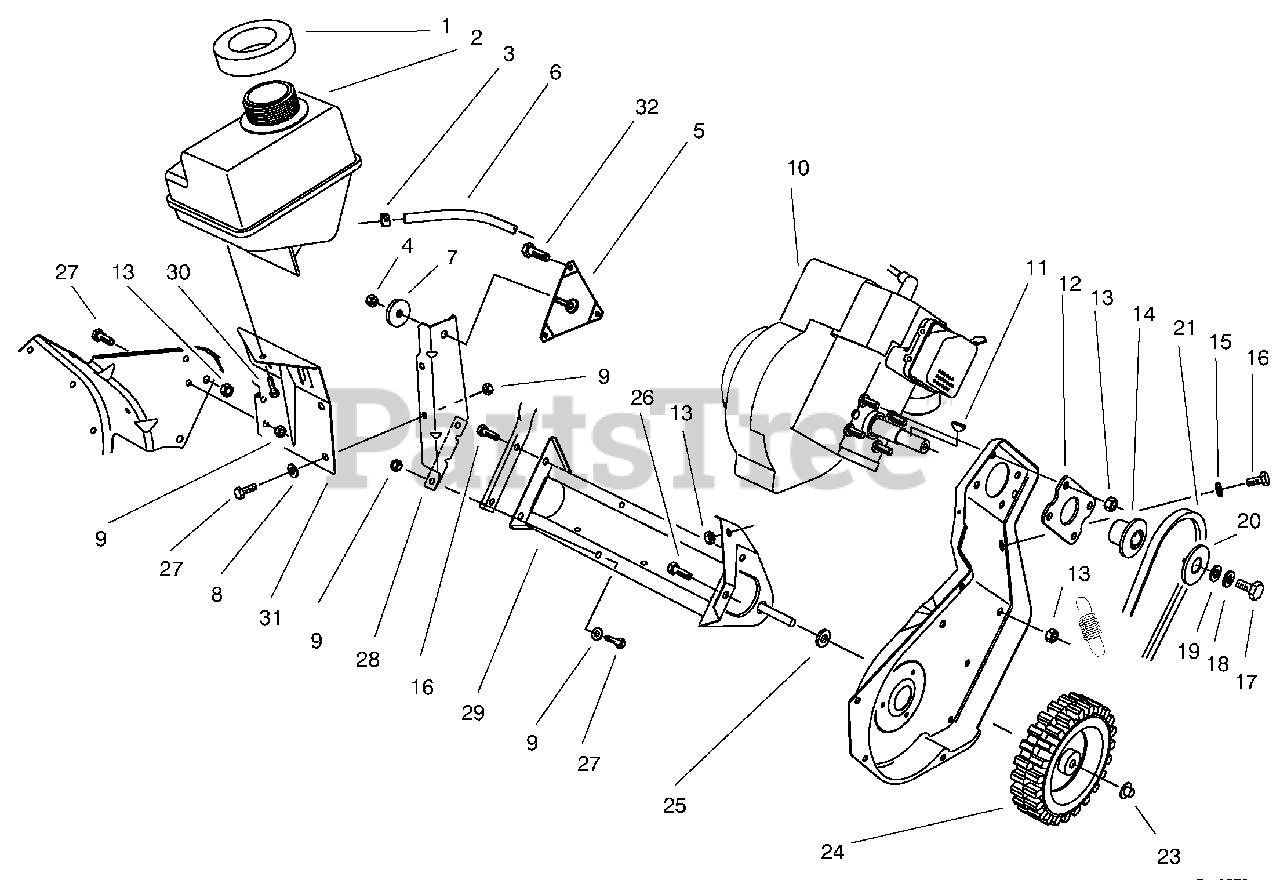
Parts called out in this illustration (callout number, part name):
1	Seal-Fuel Tank
2	Tank-Fuel
3	Clamp-Hose
4	Nut-Lock
5	Bracket-& Stud Assembly
6	Hose-Fuel
7	Washer-Engine Support
8	Washer-Flat
9	Nut-Lock
11	Key-Woodruff
12	Plate-Engine
13	Nut-Lock
14	Hub-Sheave
15	Washer-Flat
16	Screw-Hex. Hd.
17	Screw-Locking Hex. Hd.
18	Washer-Belleville
19	Washer-Flat
20	Cap-Sheave
21	Belt-Drive
25	Spacer-Wheel
26	Screw-Hex. Hd.
27	Screw-Hex. Hd.
28	Support-Engine
29	Frame Assembly
30	Screw-Thread Forming
31	Bracket-Fuel Tank
32	Screw-Thread Form.
